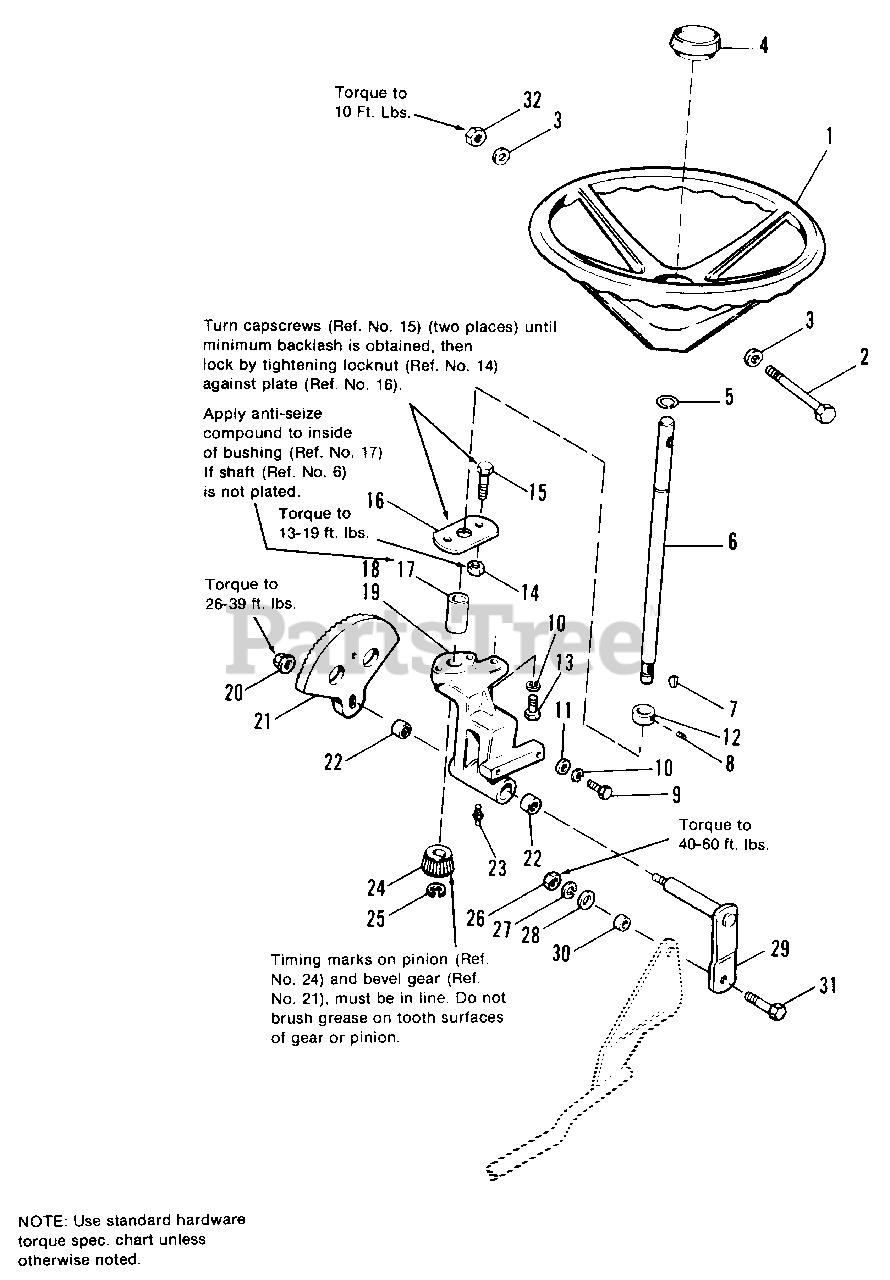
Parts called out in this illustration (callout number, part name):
1	WHEEL, Steering
2	BOLT, Hex, 5/16 x 3-1/2
3	WASHER, 5/16
4	CAP, Steering Wheel
5	RING, Retaining
6	SHAFT, Steering
7	KEY, Woodruff, #6
8	SETSCREW, 5/16-18 x 1/4
9	CAPSCREW, Hex Hd., 3/8-16 x 7/8
10	LOCKWASHER, 3/8
11	WASHER, Plain, 3/8
12	COLLAR, Set
13	CAPSCREW, Hex Hd., 3/8-16 x 3/4
14	LOCKNUT, Hex, Jam, 3/8-16
15	CAPSCREW, Hex Hd., 3/8-16 x 1-1/4
16	PLATE, Steering
18	HOUSING ASSY., Steering (Incl. Ref. Nos. 17 & 22)
19	HOUSING ASSY., Steering
20	LOCKNUT, Hex, Flange, 7/16-14
21	GEAR, Bevel
22	BEARING, Needle
23	FITTING, Grease
24	PINION, Bevel
25	E-RING
26	NUT, Hex, Full, 1/2-13
27	LOCKWASHER, 1/2
28	WASHER, Plain, 1/2
29	ARM ASSY., Steering
31	CAPSCREW, Hex Hd., 1/2-13 x 1-1/2
32	LOCKNUT, Hex, Cntr. 5/16-18
